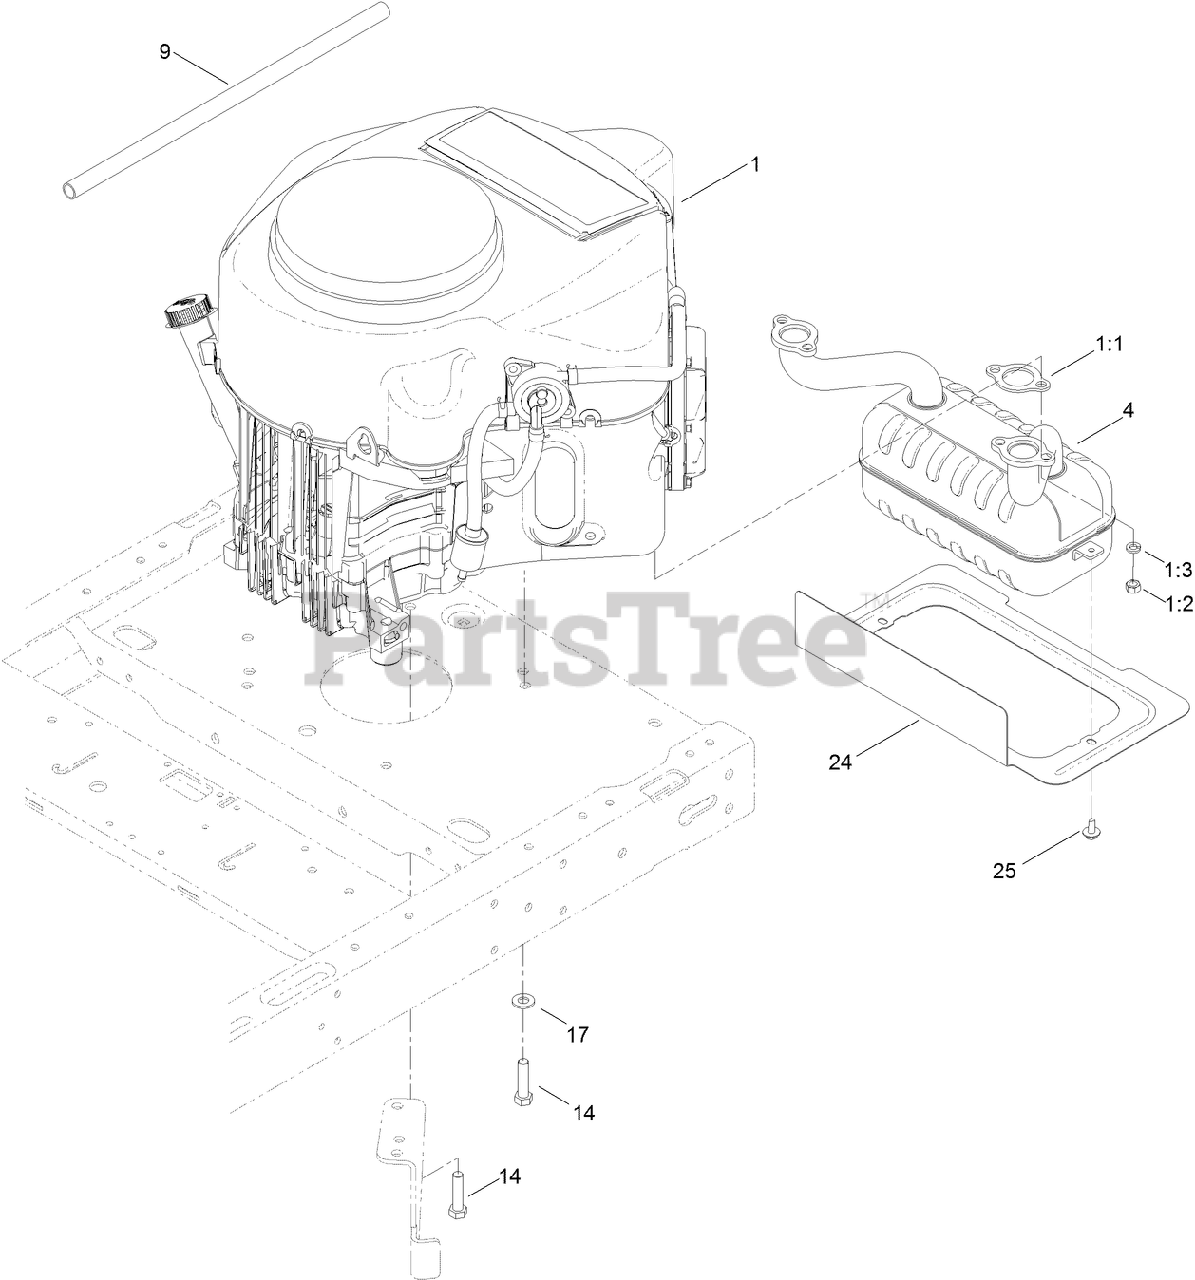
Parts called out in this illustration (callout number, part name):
1:1	GASKET-EXHAUST
1:3	WASHER-LOCK
4	MUFFLER-KAWASAKI
9	TUBE-DRAIN, OIL
14	BOLT-HH
17	WASHER-FLAT
24	SHIELD-HEAT
25	SCREW-HHFTF
